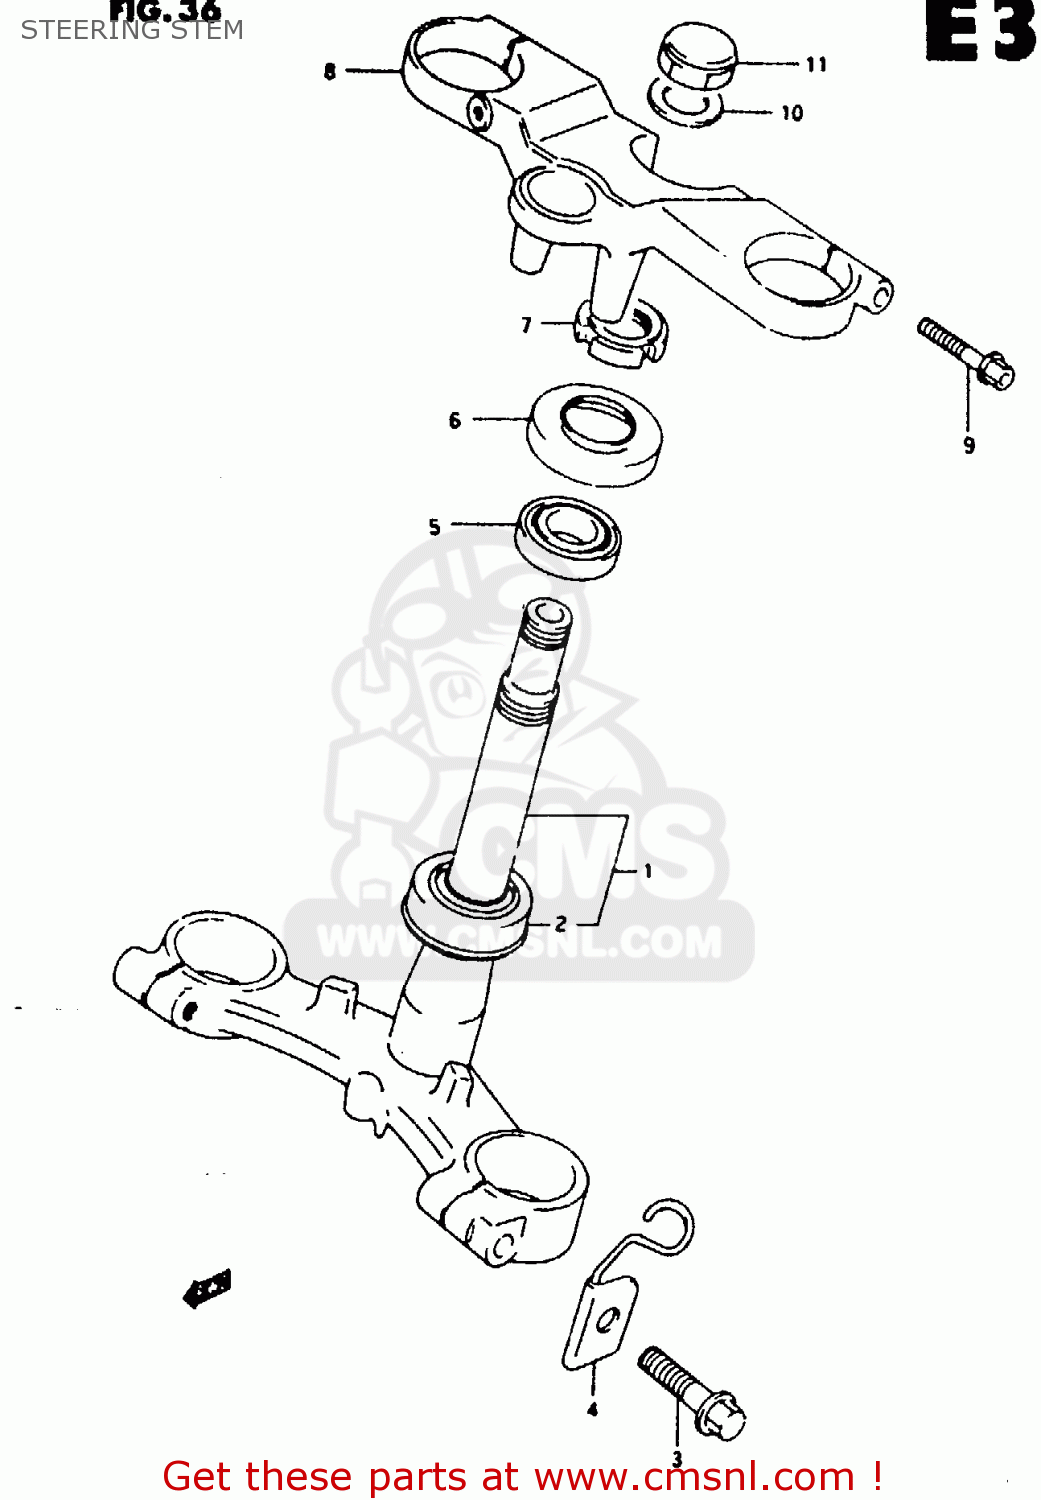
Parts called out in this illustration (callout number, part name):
1	STEM,STEERING
2	BEARING(30X55X17)
3	BOLT
4	CLAMP,SPEEDOMETER CABLE
5	TAPER,ROLLER BEARING
6	DUST SEAL,STEERING UPR
7	NUT,STEERING STEM(25X44X10)
8	HEAD,STEERING STEM
9	BOLT 8X40
10	WASHER
11	NUT,CAP
